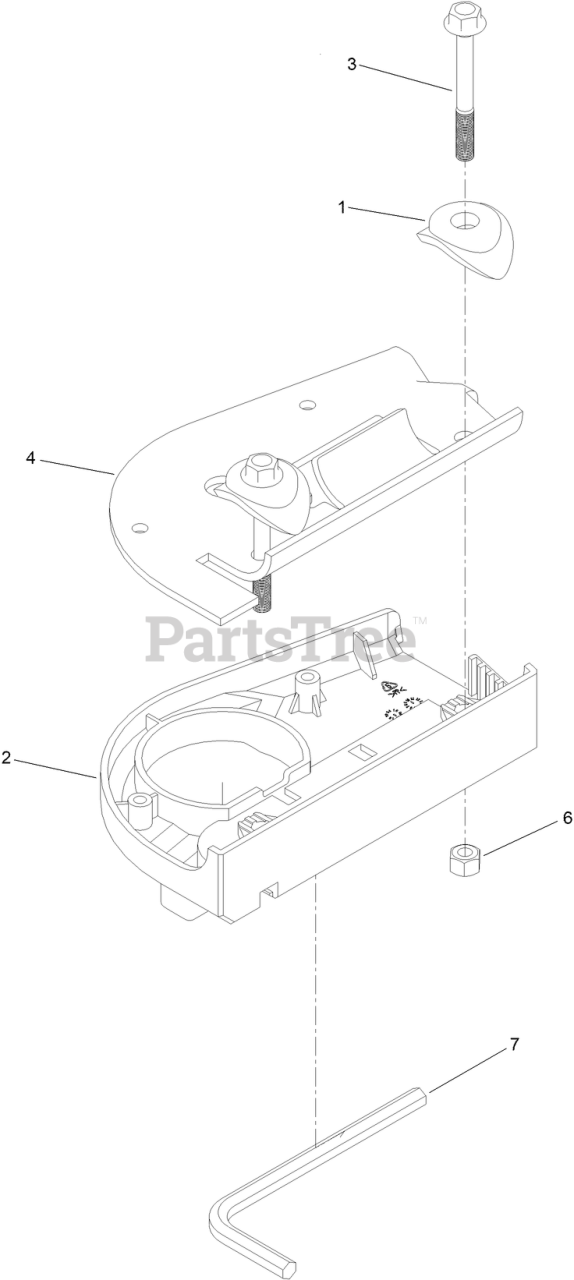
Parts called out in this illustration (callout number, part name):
1	WASHER-CURVE
2	CASING - LEVER
3	BOLT-FLANGE, HEX
4	PLATE-BRACKET, LEVER RAISE TINE
6	NUT-HEX
7	KEY- ALLEN, HEX
